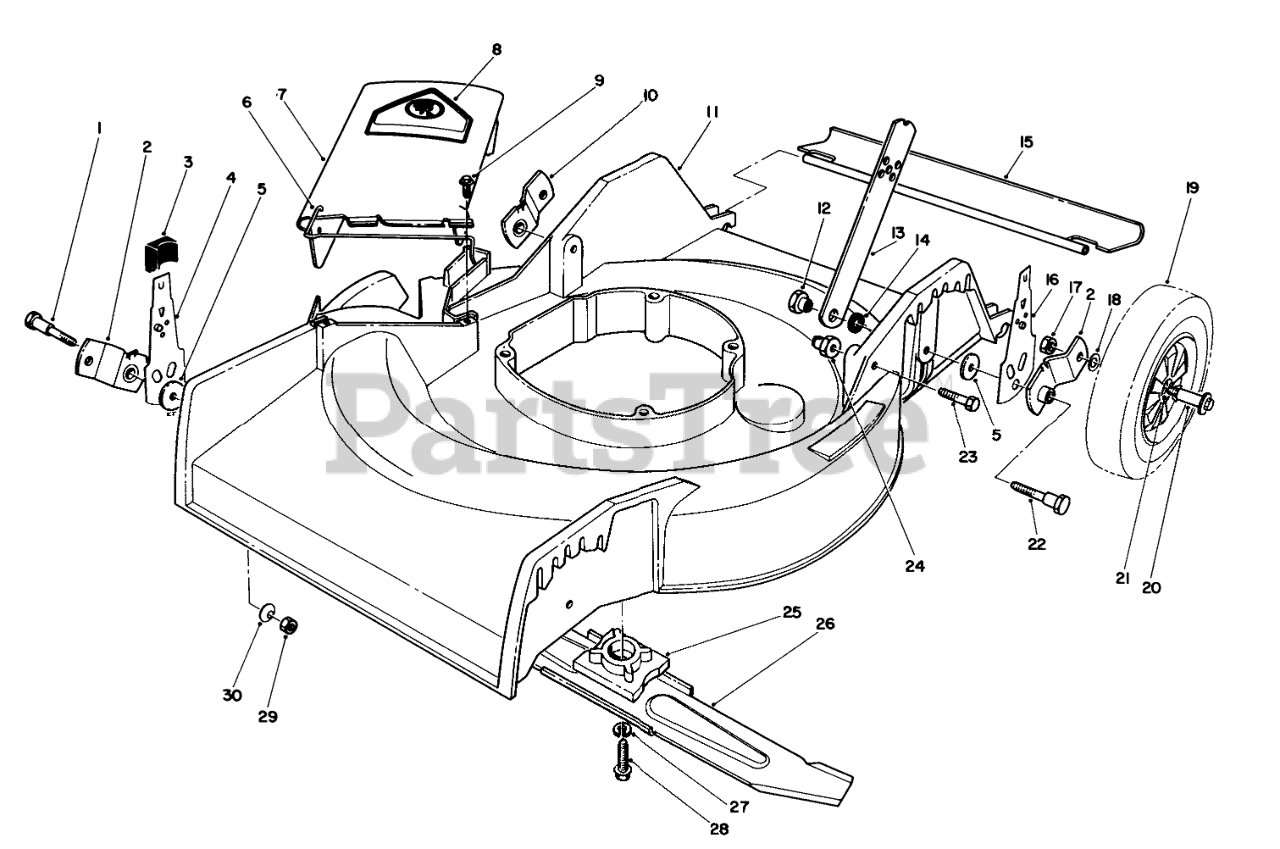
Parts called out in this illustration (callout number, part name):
1	5/16-18 PIVOT SCREW
2	Pivot Arm
3	KNOB-ARM
4	RH FRONT SPRING ARM ASM
5	PIVOT WASHER
6	SPRING HINGE
7	Deflector (Incl. Ref. #6 & 8)
8	DECAL-DANGER
9	SCREW-HWH
10	Pivot Arm
11	HOUSING W/ DECAL
12	HANDLE PIVOT NUT
13	HANDLE LATCH
14	SPACER
15	SHIELD - TRAILING
16	REAR SPRING ARM ASM
17	Nut
18	WASHER
19	Wheel & Tire Assembly (Incl. Ref. #21)
20	BOLT-WHEEL
21	BUSHING
22	PIVOT SCREW
23	SCREW-HH
24	HANDLE PIVOT NUT
25	BLADE RETAINER
26	Blade
27	WASHER-LOCK
28	SCREW-HH
29	NUT-LOCK, NI
30	WASHER-BELLEVILLE
